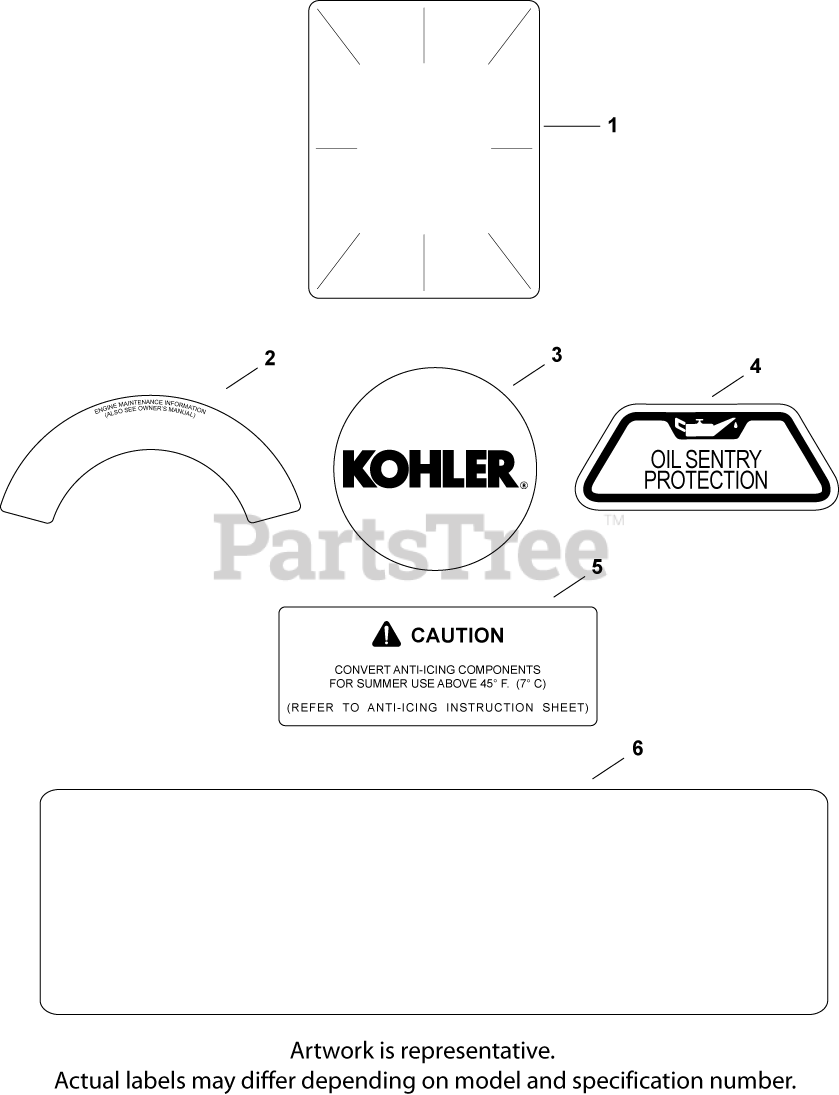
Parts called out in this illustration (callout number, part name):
1	DECAL, CLEAR LAMINATE USE 25 113 70-S
2	DECAL, ENGINE MAINTENANCE-DISC.
3	LABEL, (ROUND KOHLER GOLD)-USE 24 113 18
4	DECAL, OIL SENTRY - (#DSC)
5	DECAL, ANTI-ICING
6	DECAL, 23 HP - (#24113216S)
